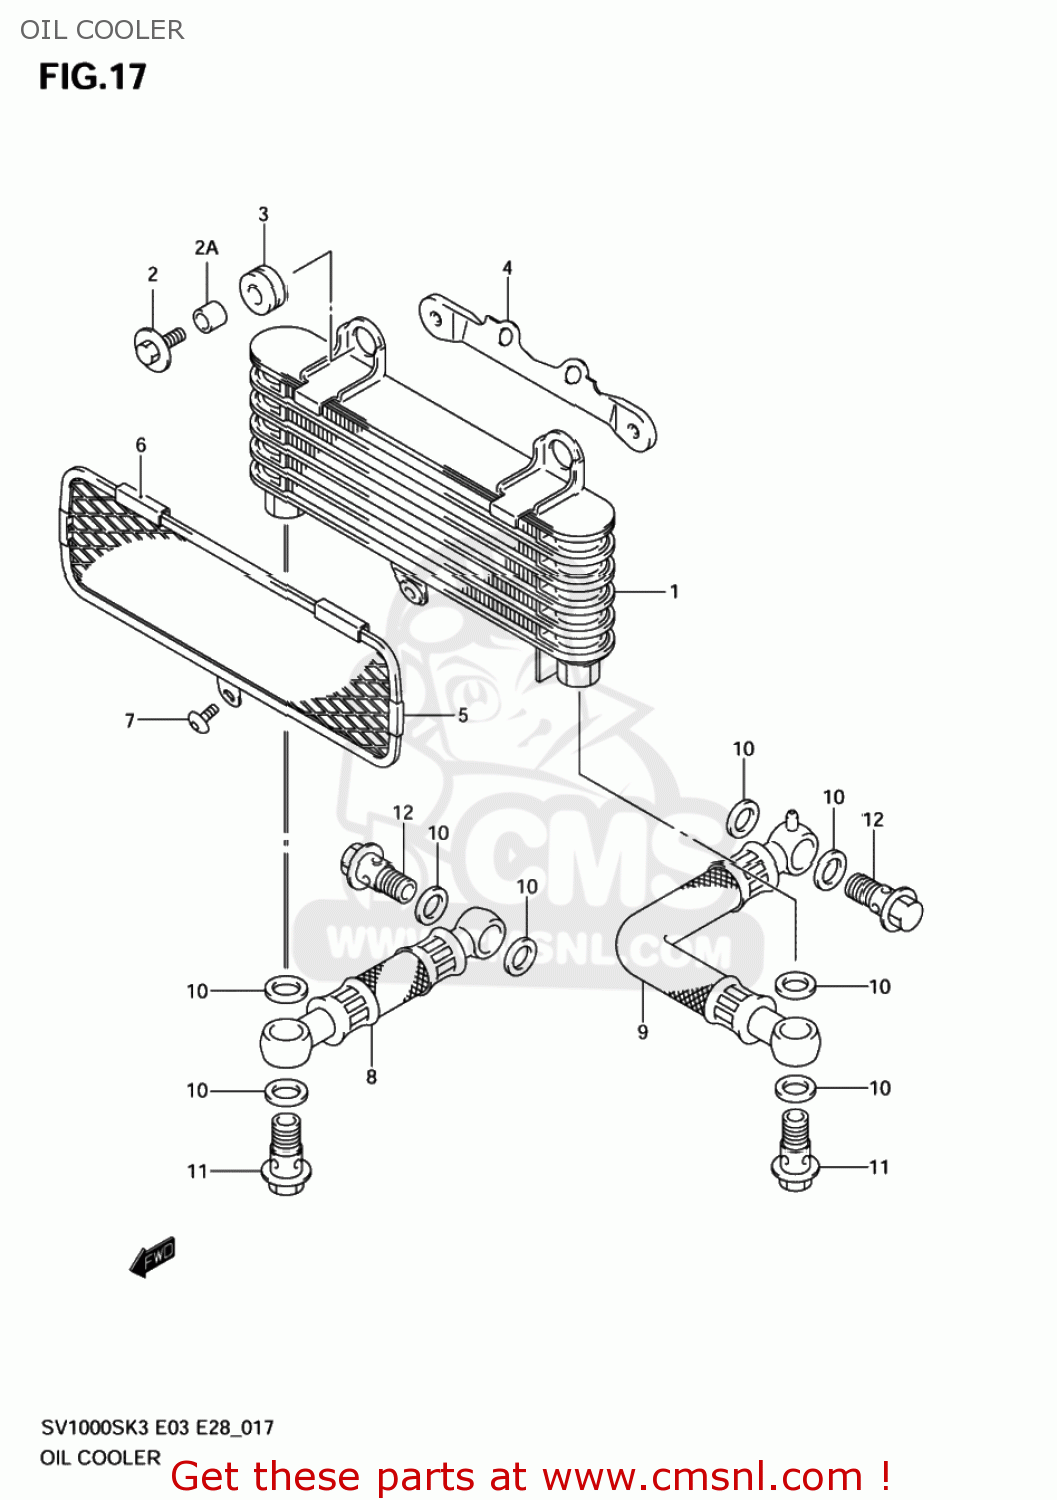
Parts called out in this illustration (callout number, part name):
1	COOLER ASSY,OIL
2	BOLT(6X20)
2A	SPACER(6.5X10X10)
3	CUSHION
4	BRACKET,OIL COOLER
5	GUARD,OIL COOLER
6	PROTECTOR,CTR
7	SCREW
8	HOSE,OIL COOLER,R
9	HOSE,OIL COOLER,L
10	GASKET(14X20X1.5) (NAS)
11	BOLT UNION
12	BOLT UNION
